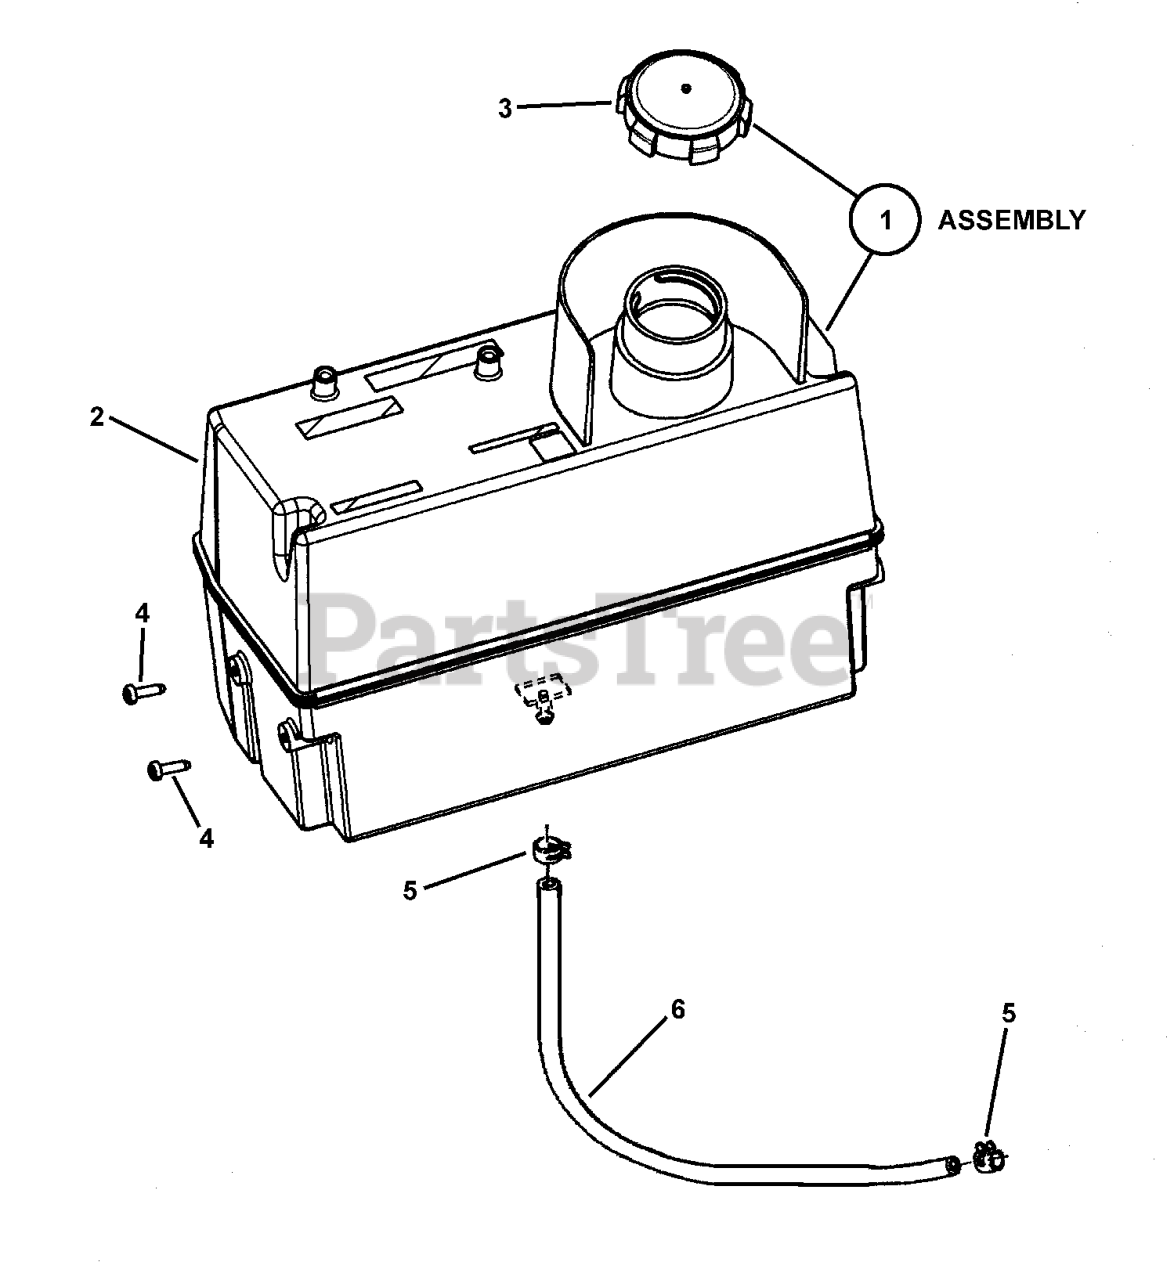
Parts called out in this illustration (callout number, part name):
1	TANK, FUEL TANK W/ CAP (MURRAY)
2	TANK, FUEL 2.8 GAL
3	CAP, FUEL TANK
4	SCREW, THREAD FORMING, 0.88 X 3/16-15
5	HOSE CLAMP, YELLOW
6	HOSE, FUEL, LOW PERM, 1/4" ID X 17"
